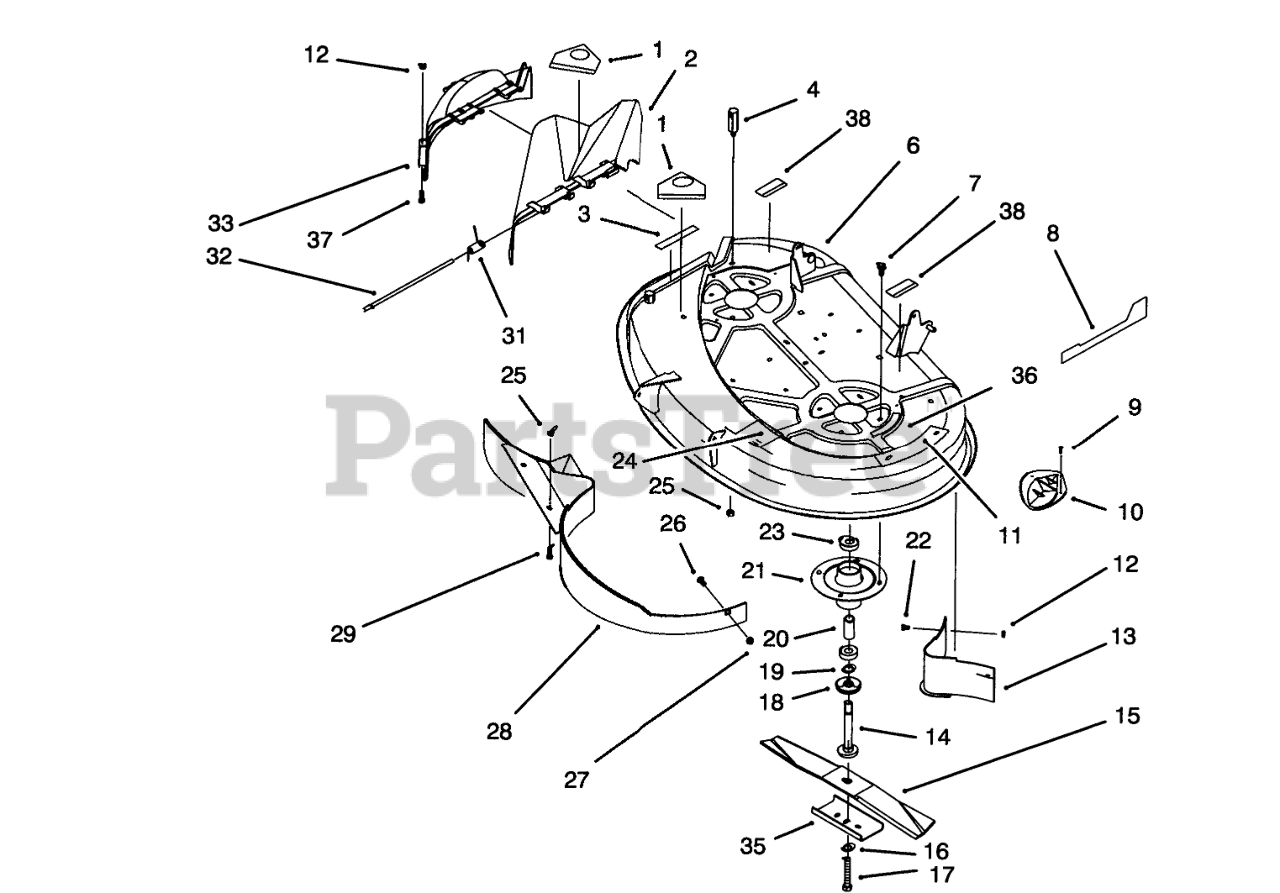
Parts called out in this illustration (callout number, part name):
1	DECAL-DANGER
2	Deflector-Deck
3	DECAL-DANGER, DEFLECTOR
4	REAR PIVOT POST (PLTD)
6	Deck-38"
7	SCREW-TAPTITE
8	DECAL-38" RECYCLER
9	SCREW-PPH
10	PLATE-KICKER
11	DECAL-DANGER
12	NUT-LOCK, NI
13	Baffle-Rear
14	SHAFT-SPINDLE
15	Blade
16	WASHER-BELLEVILLE
17	SCREW-HH
18	SHIELD-BEARING
19	SPACER
20	SPACER
21	HOUSING-SPINDLE
22	SCREW-HH
23	BEARING-BALL
24	Decal-Routing
25	NUT-LOCK, NI
26	BOLT-CARR
27	NUT-LOCK, NI
28	Baffle-38"
29	SCREW-HH
31	SPRING
32	ROD-HINGE DEFLECTOR
33	COVER-RECYCLER
35	Stiffener
36	DECAL-DANGER, SHIELD
37	SCREW-HH
38	DECAL-WARNING
